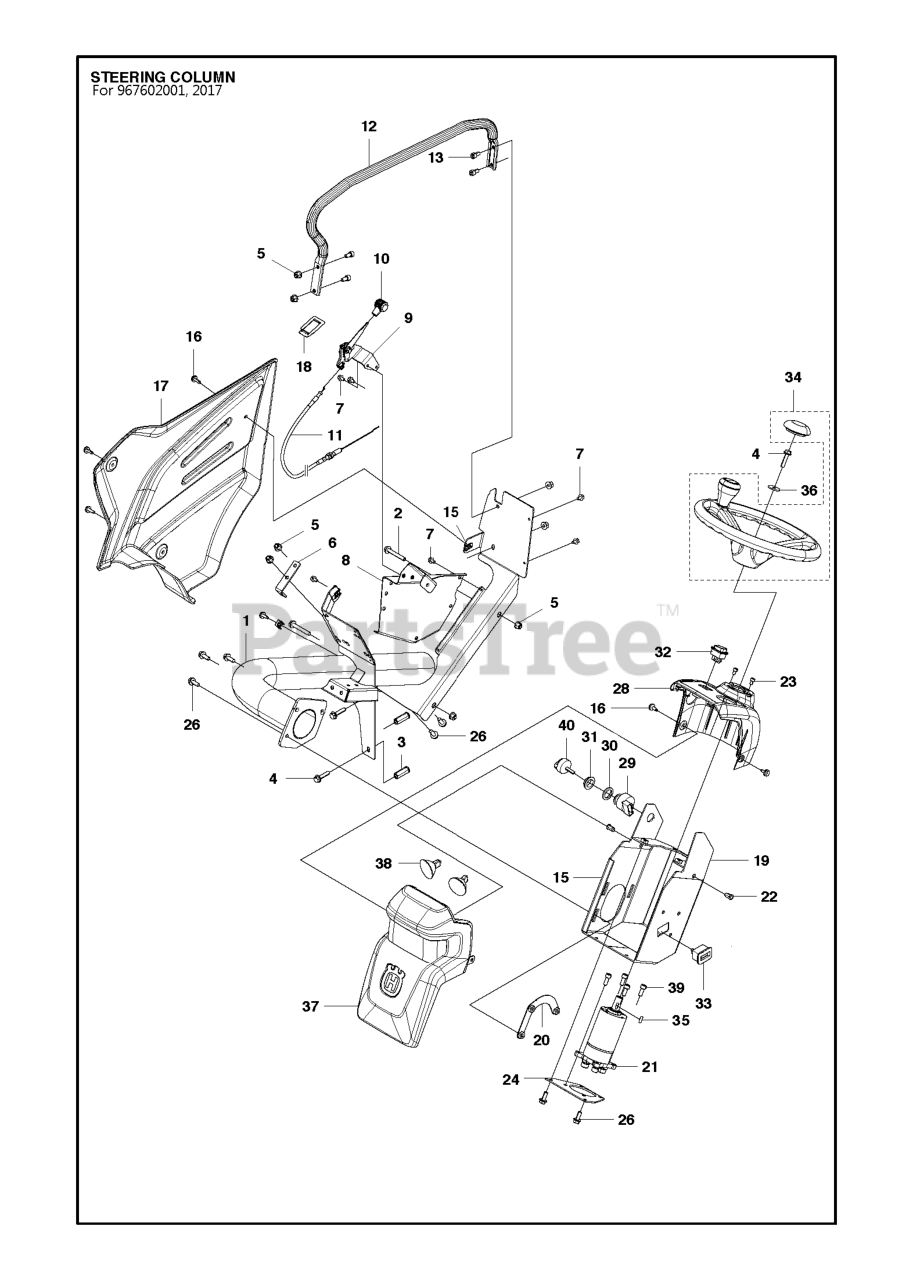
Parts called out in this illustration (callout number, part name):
2	SCREW EHHFM
4	SCREW EHHFM
5	NUT FLANGE
